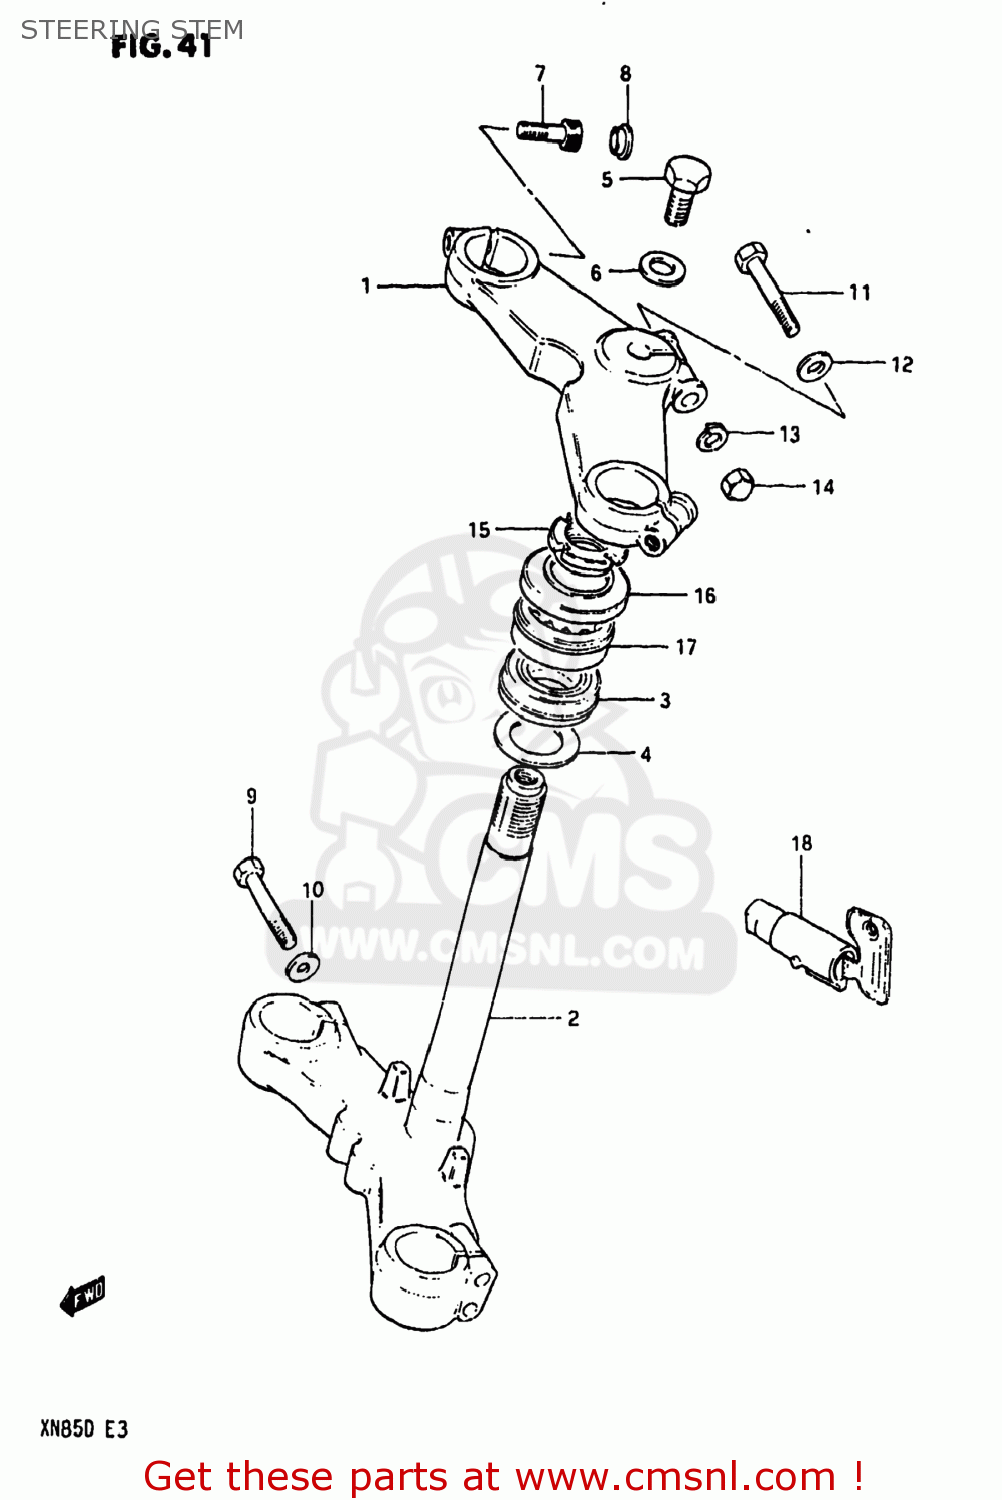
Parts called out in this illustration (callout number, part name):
1	HEAD,STEERING STEM
2	STEM,STEERING
3	BEARING
4	WASHER,THRUST
5	BOLT,STEERING STEM HEAD
6	WASHER
7	NUT,STEM HEAD
8	CAP(OD:20)
9	BOLT 8X40
10	LOCK WASHER
11	BOLT 8X50
12	WASHER
13	LOCK WASHER
14	NUT
15	NUT,STEERING STEM
16	DUST SEAL,STEERING UPR
17	TAPER,ROLLER BEARING
18	LOCK ASSEMBLY,STEERING (NEI
